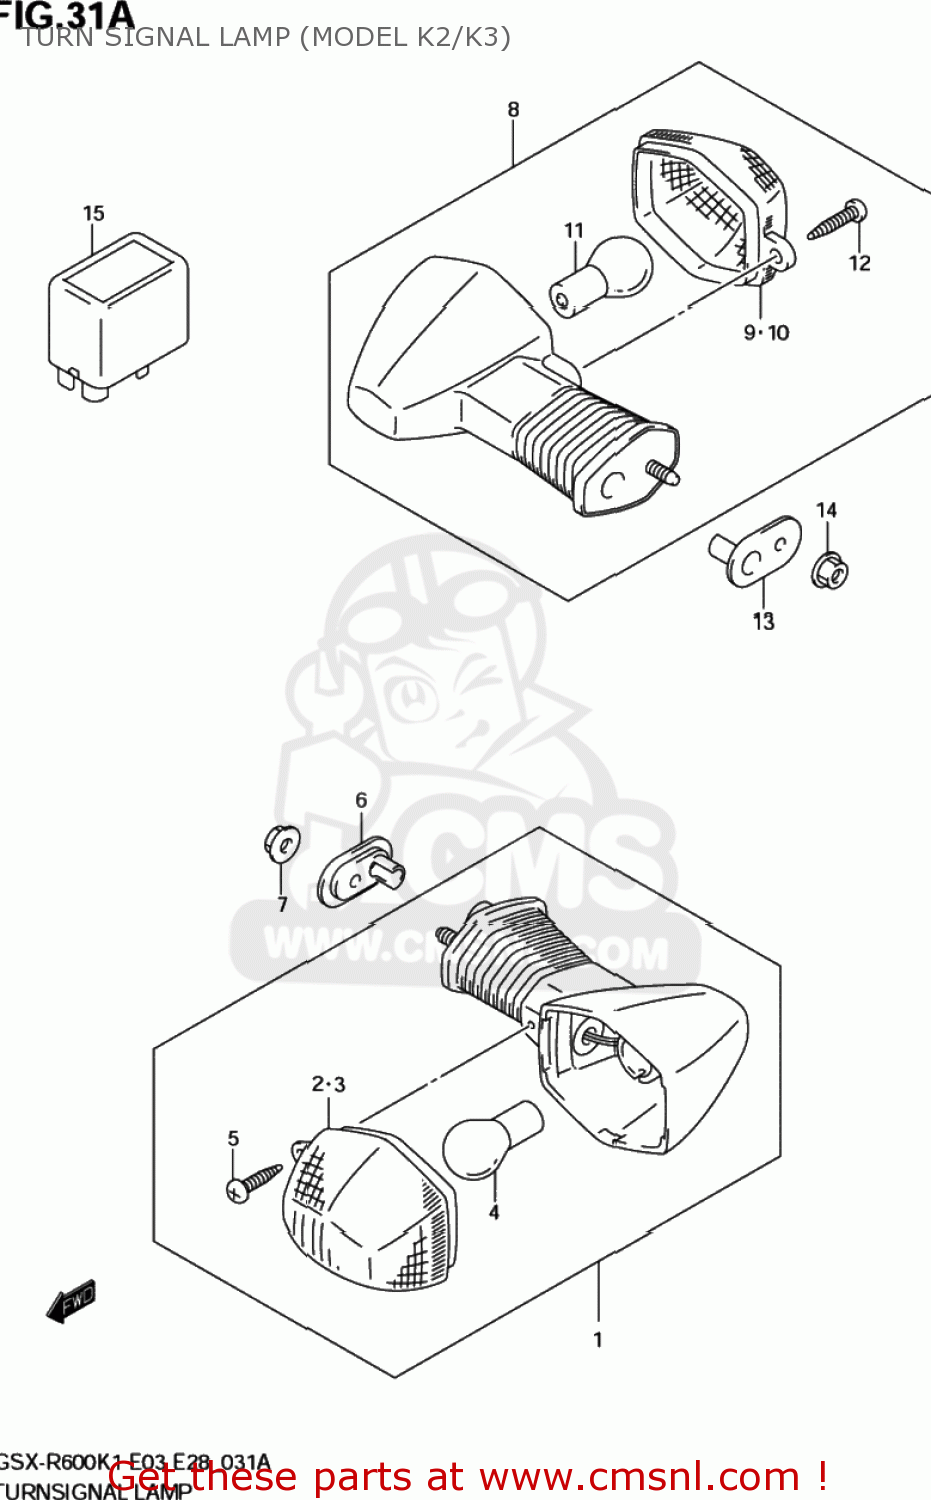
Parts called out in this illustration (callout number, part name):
1	LAMP ASSY,FR TURN SIGNAL,R
2	LENS
3	LENS
4	BULB(12V21W)
5	SCREW
6	PLATE,TURNSIGNAL LAMP
7	NUT
8	LAMP ASSY,RR TURNSIGNAL,R
9	LENS
10	LENS
11	BULB(12V21W)
12	SCREW
13	PLATE,TURNSIGNAL LAMP
14	NUT
15	RELAY ASSY,TURNSIGNAL LAMP
